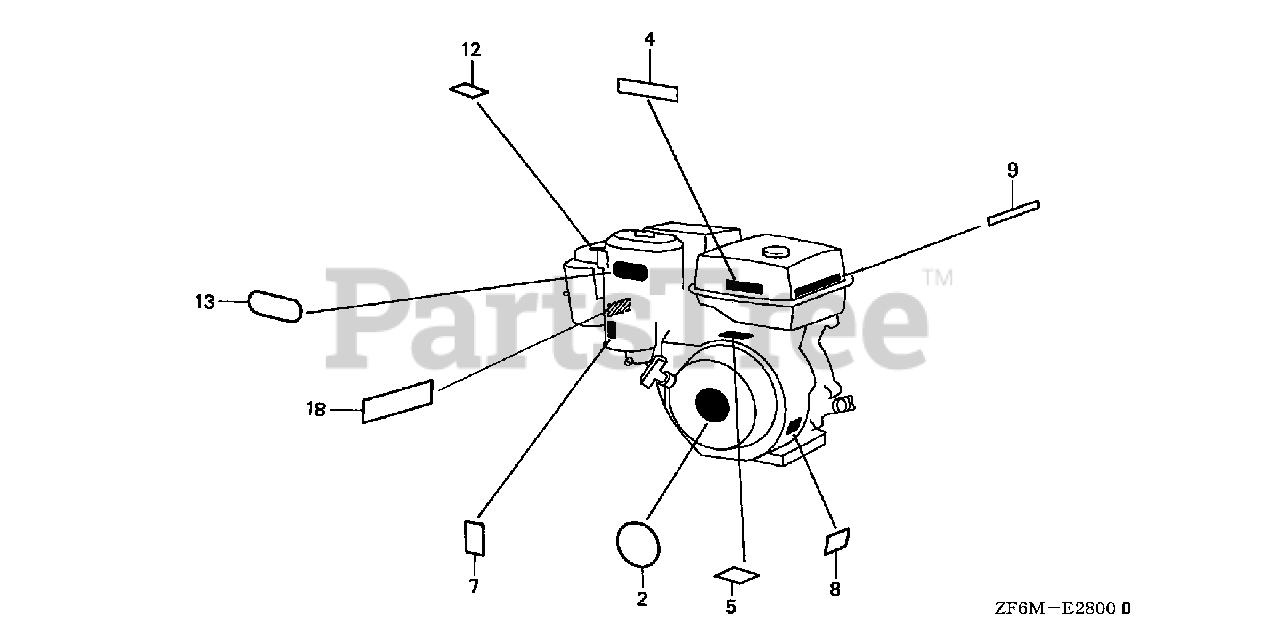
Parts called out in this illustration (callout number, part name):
2	EMBLEM
7	MARK, CHOKE
8	MARK, OIL CAUTION
18	MARK, AIR CLEANER
